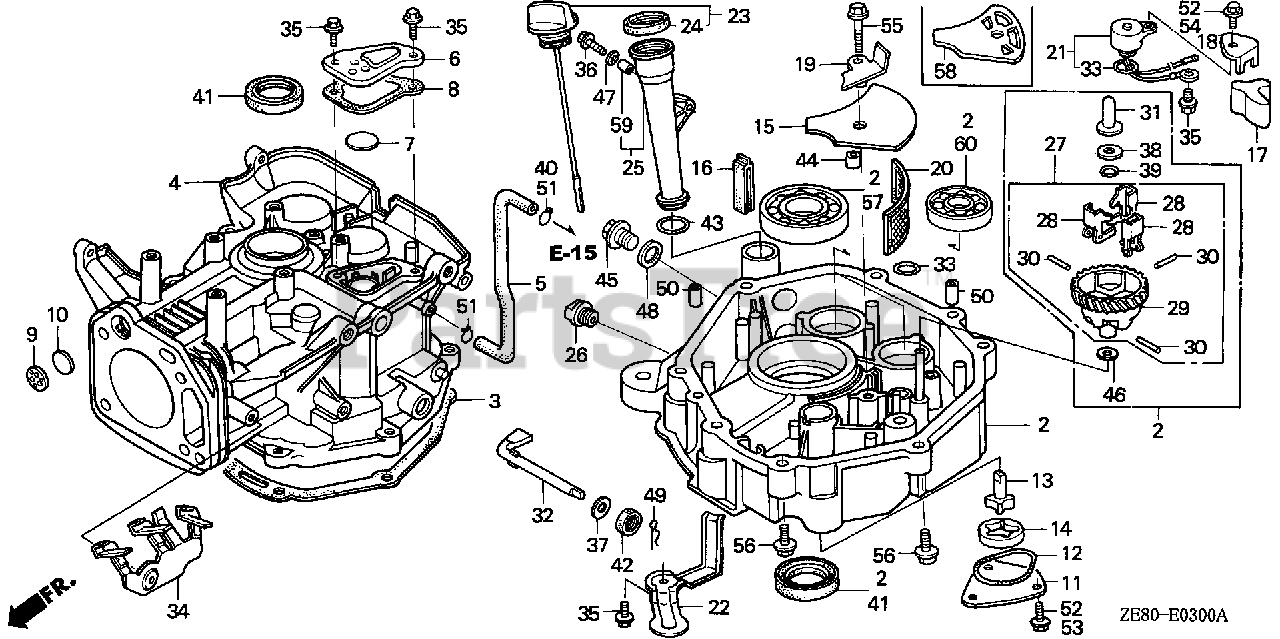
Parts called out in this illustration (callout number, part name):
2	PAN ASSY., OIL
3	GASKET, OIL PAN
4	CYLINDER
5	TUBE, BREATHER (NOT AVAILABLE)
6	CAP, BREATHER CHAMBER
7	VALVE, BREATHER
8	GASKET, BREATHER CAP
11	COVER, OIL PUMP
12	O-RING, PUMP COVER
13	ROTOR (INNER)
14	ROTOR, OIL PUMP (OUTER)
15	PLATE, OIL FILTER
16	RUBBER, OIL RETURN
17	STOPPER, OIL
18	PLATE, OIL STOPPER
19	PLATE, SUCTION
20	SCREEN, OIL FILTER
21	SWITCH, OIL LEVEL
22	PROTECTOR, SWITCH
23	CAP ASSY., OIL FILLER
24	GASKET, OIL FILLER CAP
25	EXTENSION, OIL FILLER
27	GOVERNOR ASSY. (NOT AVAILABLE)
28	WEIGHT, GOVERNOR
29	HOLDER, GOVERNOR WEIGHT
30	PIN, GOVERNOR WEIGHT
31	SLIDER, GOVERNOR
32	SHAFT, GOVERNOR ARM
33	O-RING (11.8X2.4)
34	STAY, SWITCH WIRE CLAMP (NOT AVAILABLE)
35	BOLT, FLANGE (6X12) (CT200)
36	BOLT, FLANGE (6X35) (CT200)
37	WASHER, THRUST (8.1MM)
38	WASHER (6X16)
39	CLIP, GOVERNOR HOLDER
41	OIL SEAL (30X46X8)
42	OIL SEAL (8X14X5)
43	O-RING (22.1X2.2)
45	BOLT, DRAIN PLUG (20MM)
46	WASHER, PLAIN (6MM)
47	WASHER, PLAIN (6MM)
48	WASHER, DRAIN PLUG (20MM)
49	PIN, LOCK (8MM)
50	PIN, DOWEL (8X14)
51	CLIP, TUBE (C11)
52	BOLT, FLANGE (6X12)
54	BOLT, FLANGE (6X16)
55	BOLT, FLANGE (6X25)
56	BOLT, FLANGE (8X40)
57	BEARING, RADIAL BALL (6206)
58	PLATE, OIL FILTER
60	BEARING, RADIAL BALL (6202)
